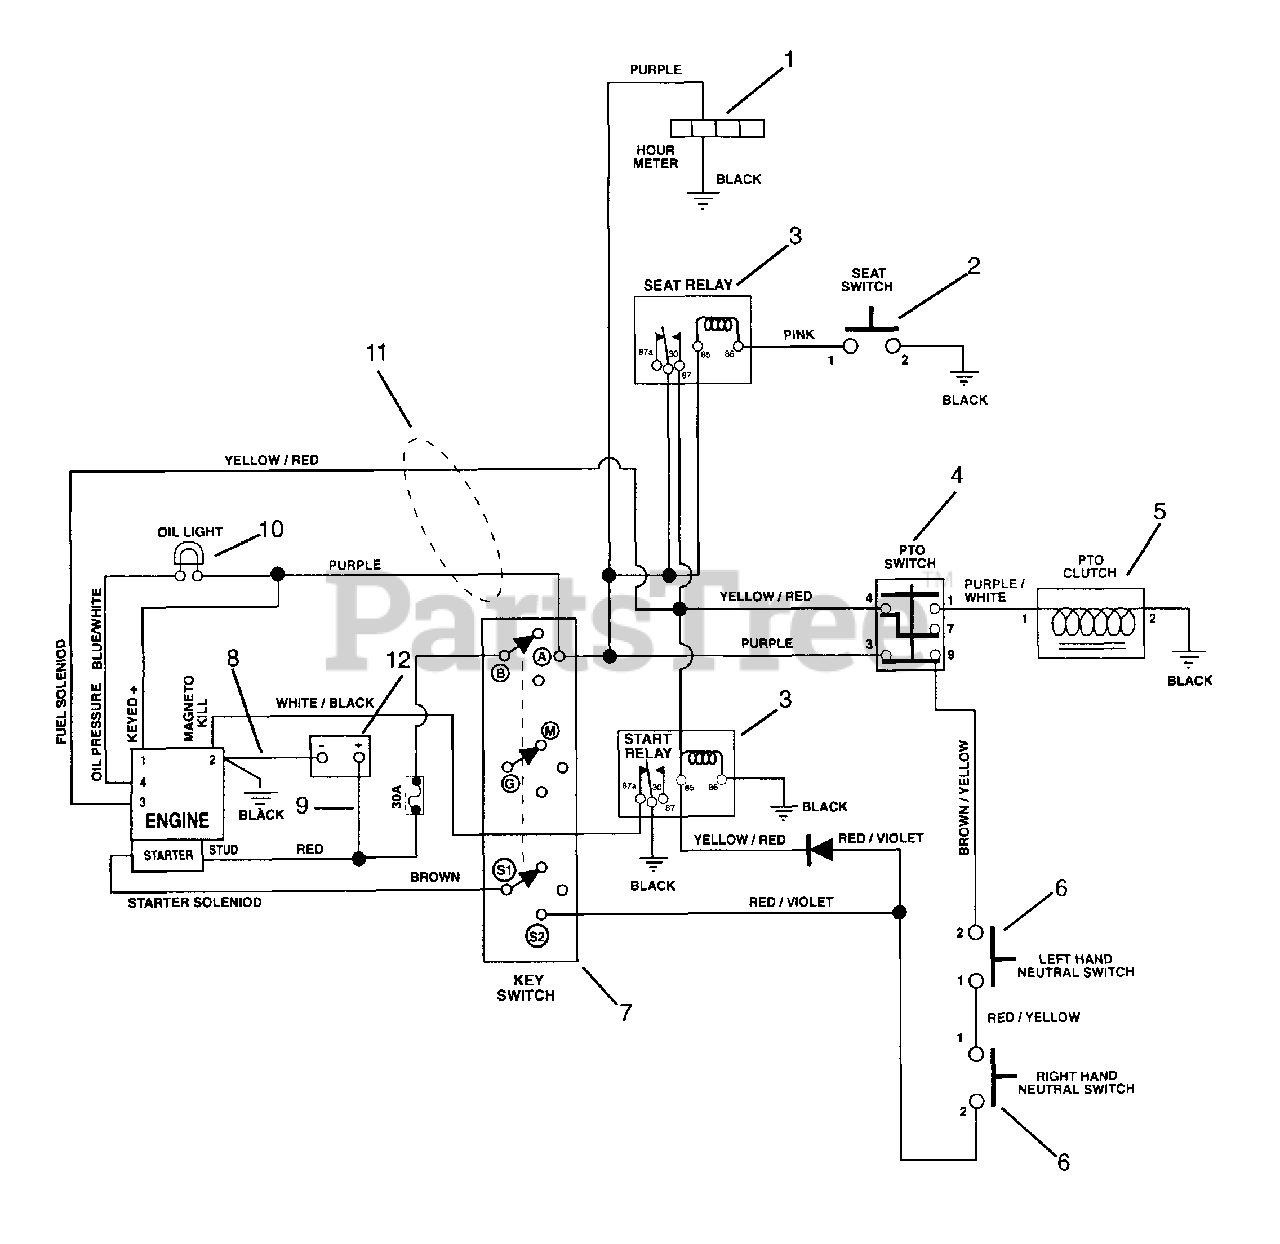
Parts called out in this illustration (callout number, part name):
1	Hour Meter
2	Switch-Seat
3	Relay
4	Switch-Clutch w/Retainer Ring
5	Clutch-Electric Warner
6	Switch-Neutral Start N.O.
7	Key Switch
8	Start Cable 22"
9	Cable-Negative Battery
10	Light-Indicator
11	Harness-Wiring 18HP Kohler
